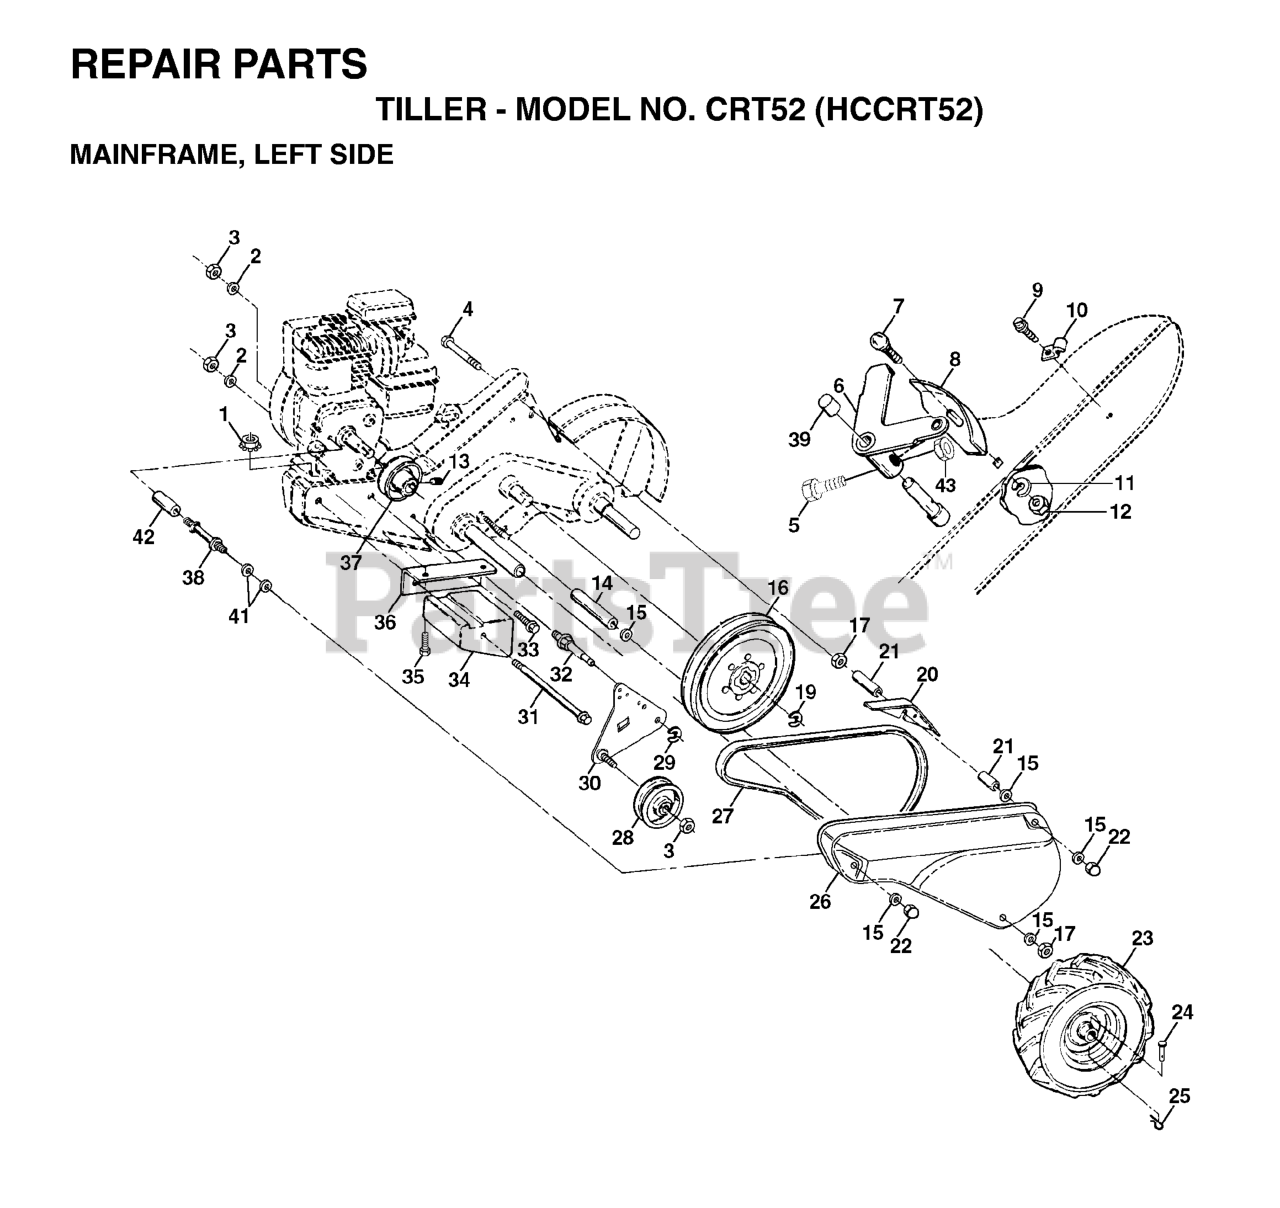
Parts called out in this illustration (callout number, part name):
1	NUT
2	WASHER, LOCK 3/8
3	NUT.HEX.3/8-16UNC
4	Bolt, Hex 5/16-18 x 4-1/4
5	SCREW, SHIFT LEVER
6	LEVER ASM CRT
8	PANEL.INDICATOR.SHIFT.BLACK
9	TAPPING SCREW
10	CONDUIT.CLIP.PLATED
11	LOCKWASHER
12	NUT
15	WASHER
16	SHEAVE, TRANSMISSION
17	NUT
19	RETAINING RING LT
21	SPACER, SPLIT
23	TIRE.16X4-8.CHEVRON.TILLER
24	RIVET,DRILLED
25	RETAINER M
26	BELT GUARD
27	V-BELT
28	PULLEY-IDLER TI
30	BRACKET ASSY TI
31	BOLT.FIN.HEX.3/8-16UNC
32	SHIFT ARM CRT
33	BOLT
34	COUNTERWEIGHT.LH.CRT
35	Bolt Fin Hex 5/16 - 18 Unc x 2 Gr. 2
36	BRACKET LH CRT
37	RP.ENGINE PULLEY
38	BELT GUARD STUD
39	CAP.PLUNGER.BLACK
532124366	RIM
532124718	VALVE STEM LT
